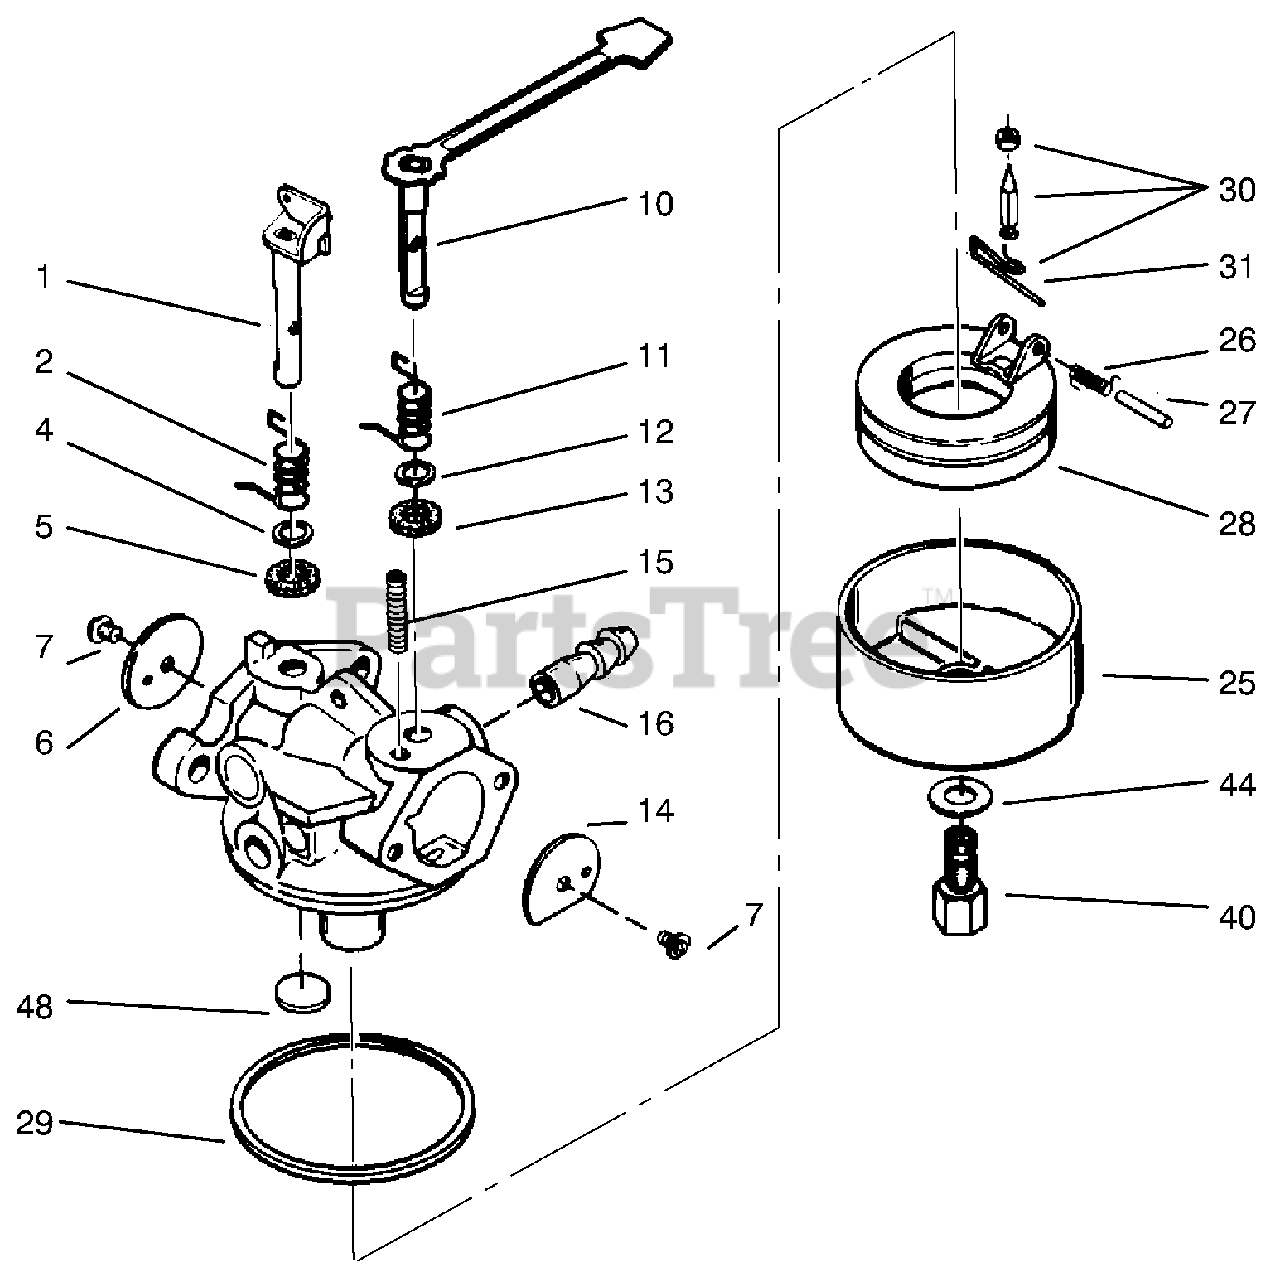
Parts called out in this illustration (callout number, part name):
1	Throttle Shaft & Lever Asm.
2	Throttle Return Spring
4	Dust Seat Washer
5	Dust Seat (Throttle)
6	Throttle Shutter
7	Shutter Screw
10	Choke Shaft & Lever Asm. (Incl. Ref. # 11-13)
14	Choke Shutter
15	Choke Positioning Spring
16	Fuel Fitting
25	Float Bowl
26	Float Dampening Spring
27	Float shaft
29	Float Bowl "O" Ring
30	Inlet Needle, Seat & Clip (Incl. Ref. #31)
31	Spring Clip
40	High Speed Bowl Nut
44	Bowl Nut Washer
48	Welch Plug
